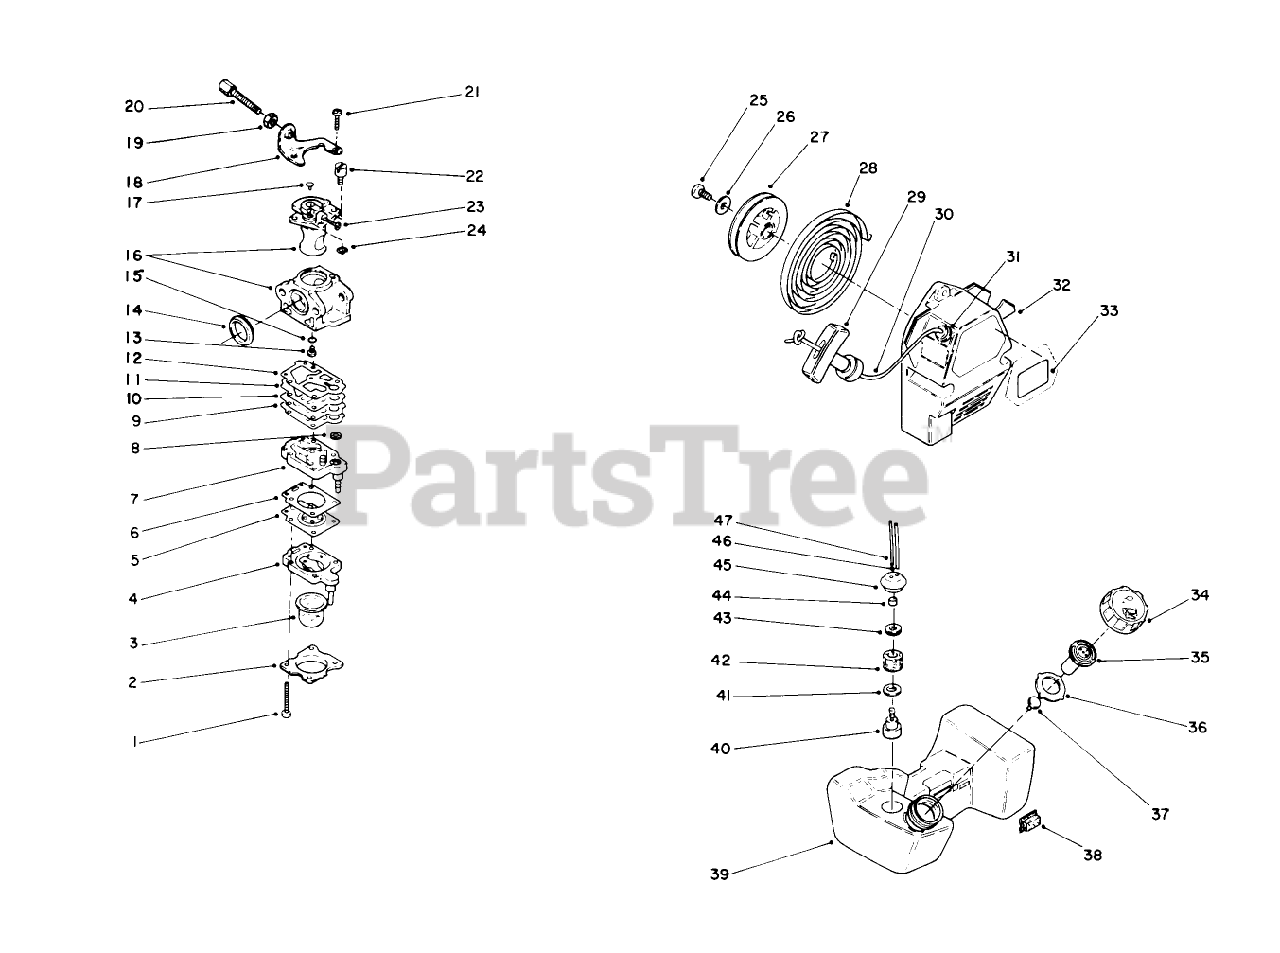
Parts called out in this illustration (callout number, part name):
3	PRIMER PUMP
5	DIAPHRAGM
6	DIAPHRAGM GASKET
7	PUMP BODY
8	SCREEN
9	PUMP GASKET
11	DIAPHRAGM
12	DIAPHRAM GASKET
14	RUBBER CARB GASKET
15	MAIN JET O-RING
16	Body-Carburator-(Ref.)
18	BRACKET
23	THROTTLE VALVE
34	FUEL TANK CAP
35	BREATHER VALVE
36	PACKING
44	COLLAR
45	FUEL TANK GROMMET
47	RETURN FUEL HOSE
